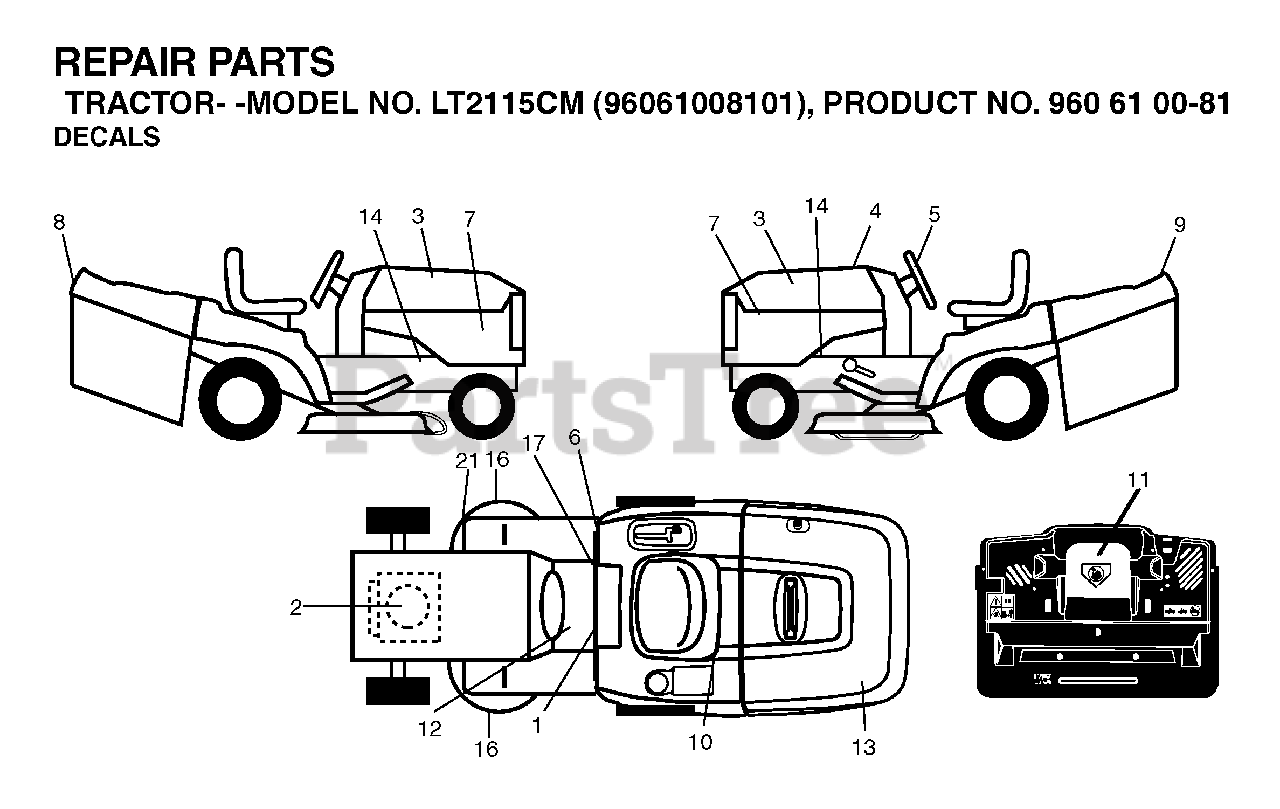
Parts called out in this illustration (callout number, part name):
8	DECAL.FENDER.LT2115CM
10	DECAL BTRY SYMBOLS
11	DECAL.INTERNATIONL.CUTFINGER
17	DECAL PARK BRAKE
